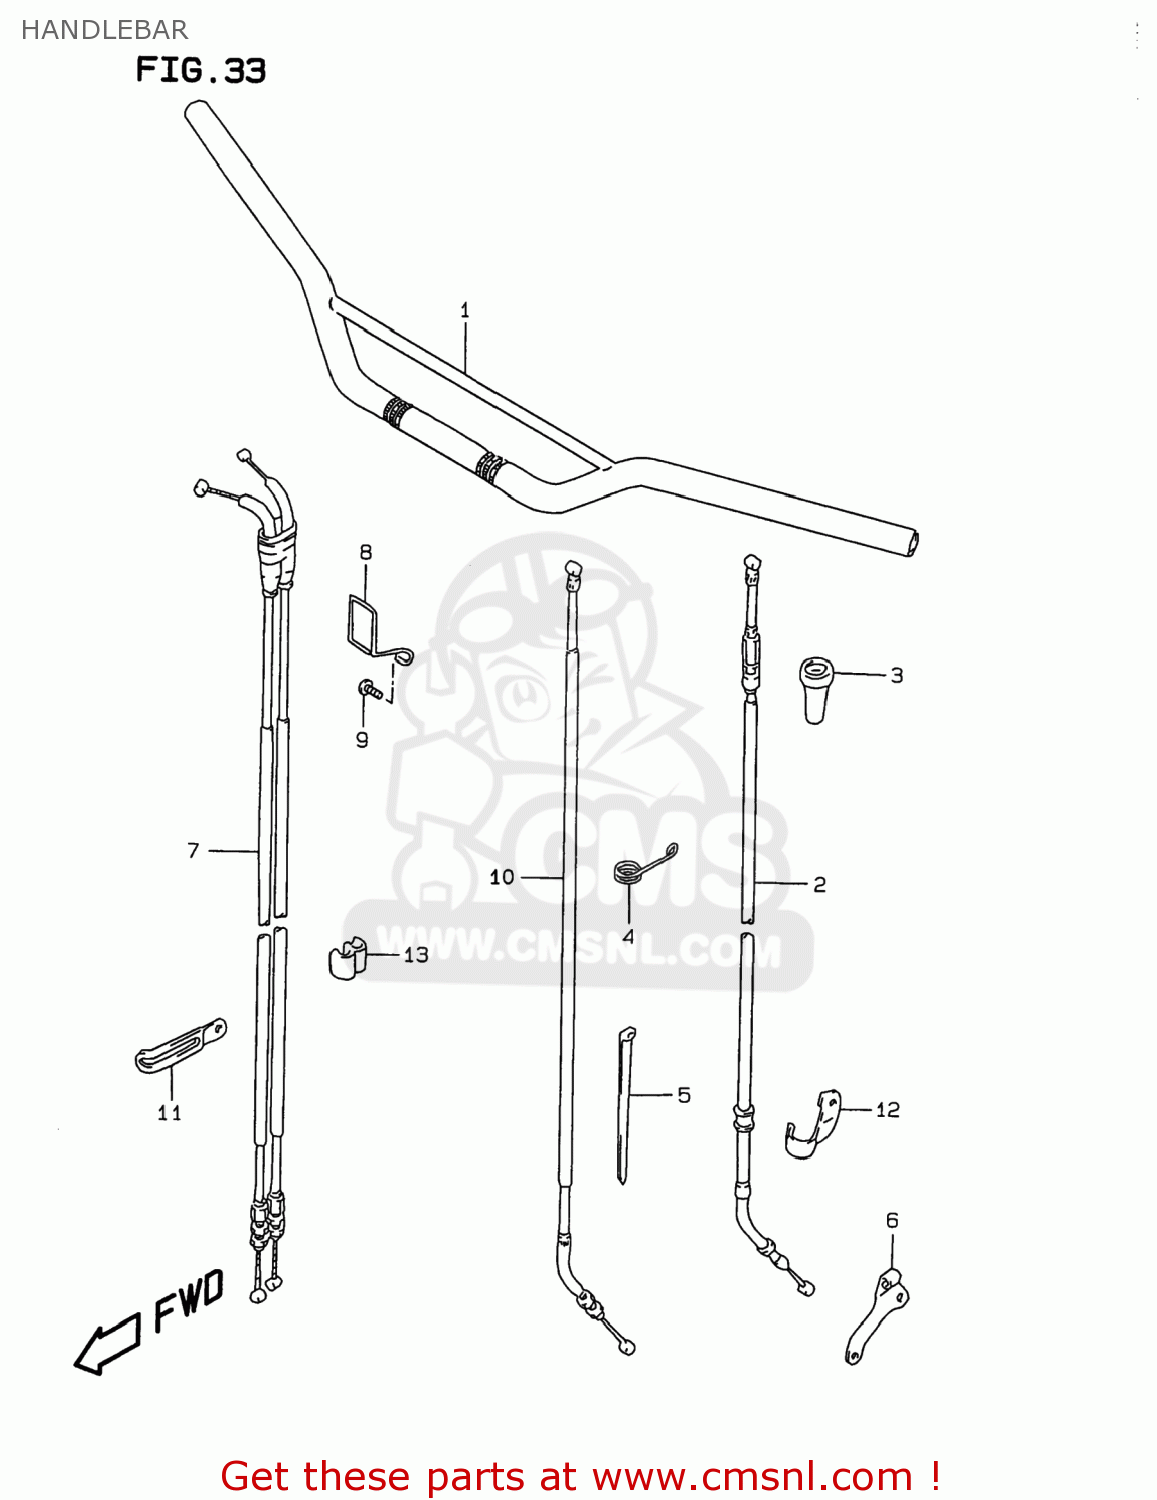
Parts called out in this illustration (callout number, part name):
1	HANDLEBAR(BLACK)
2	CABLE ASSY,CLUTCH
3	BOOT,CLUTCH CABLE
4	GUIDE,CLUTCH CABLE
5	CLAMP(L:145)
6	STOPPER,CLUTCH CABLE
7	CABLE SET,THROTTLE
8	GUIDE,CABLE
9	BOLT
10	CABLE ASSY,DECOMP
11	CLAMP(L:65)
12	CLAMP,CLUTCH CABLE
13	CLIP
